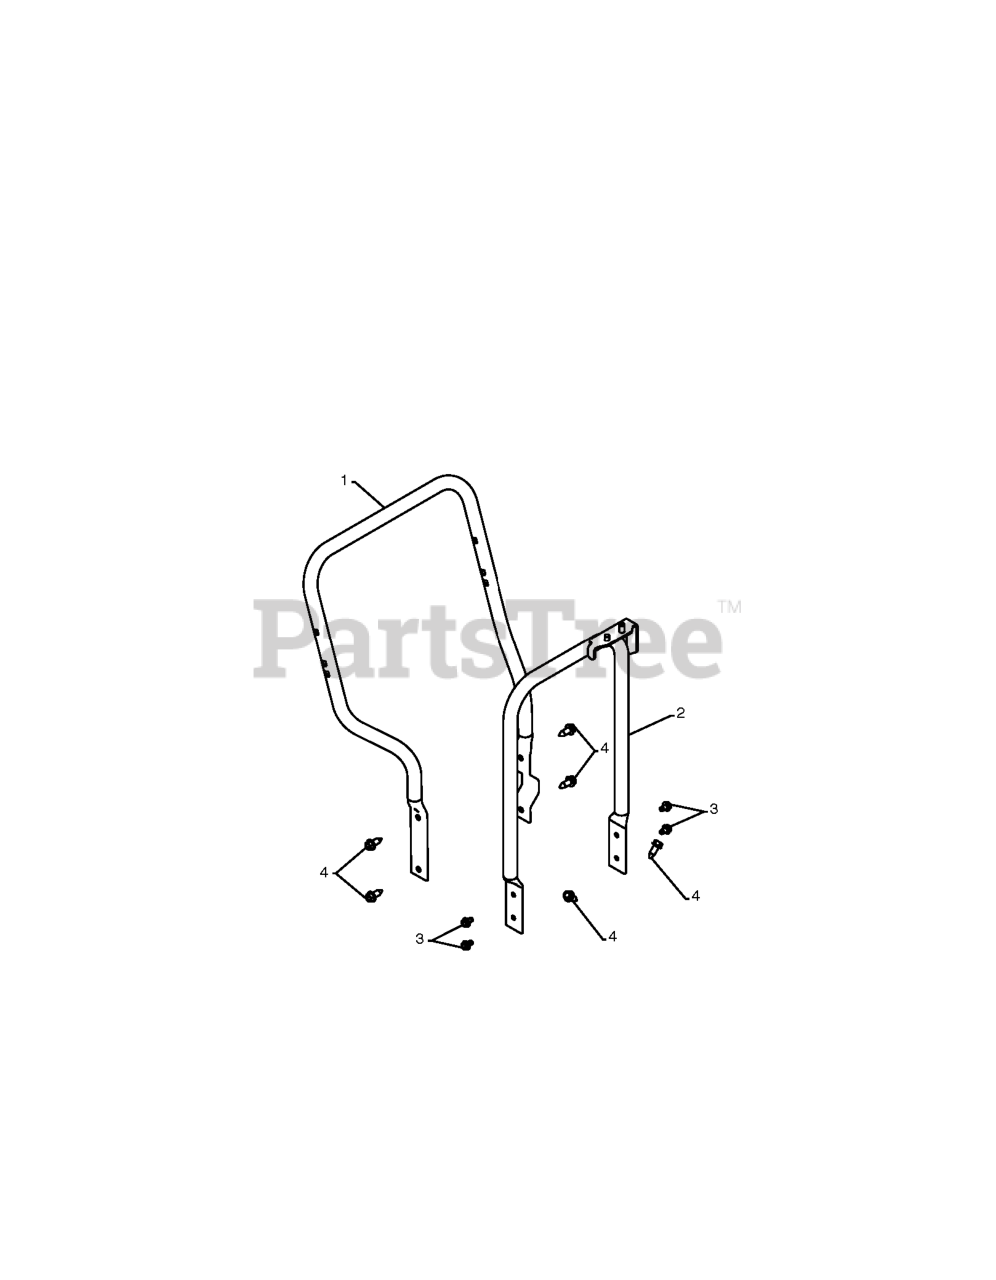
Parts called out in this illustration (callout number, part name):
1	TUBE.LOWER.HANDLE.SNOW.GRAY
2	SUPPORT, PIVOT
3	SELF-TAPPING SCREW 5/16-18X3/4
4	SCREW 3/8-16X1
